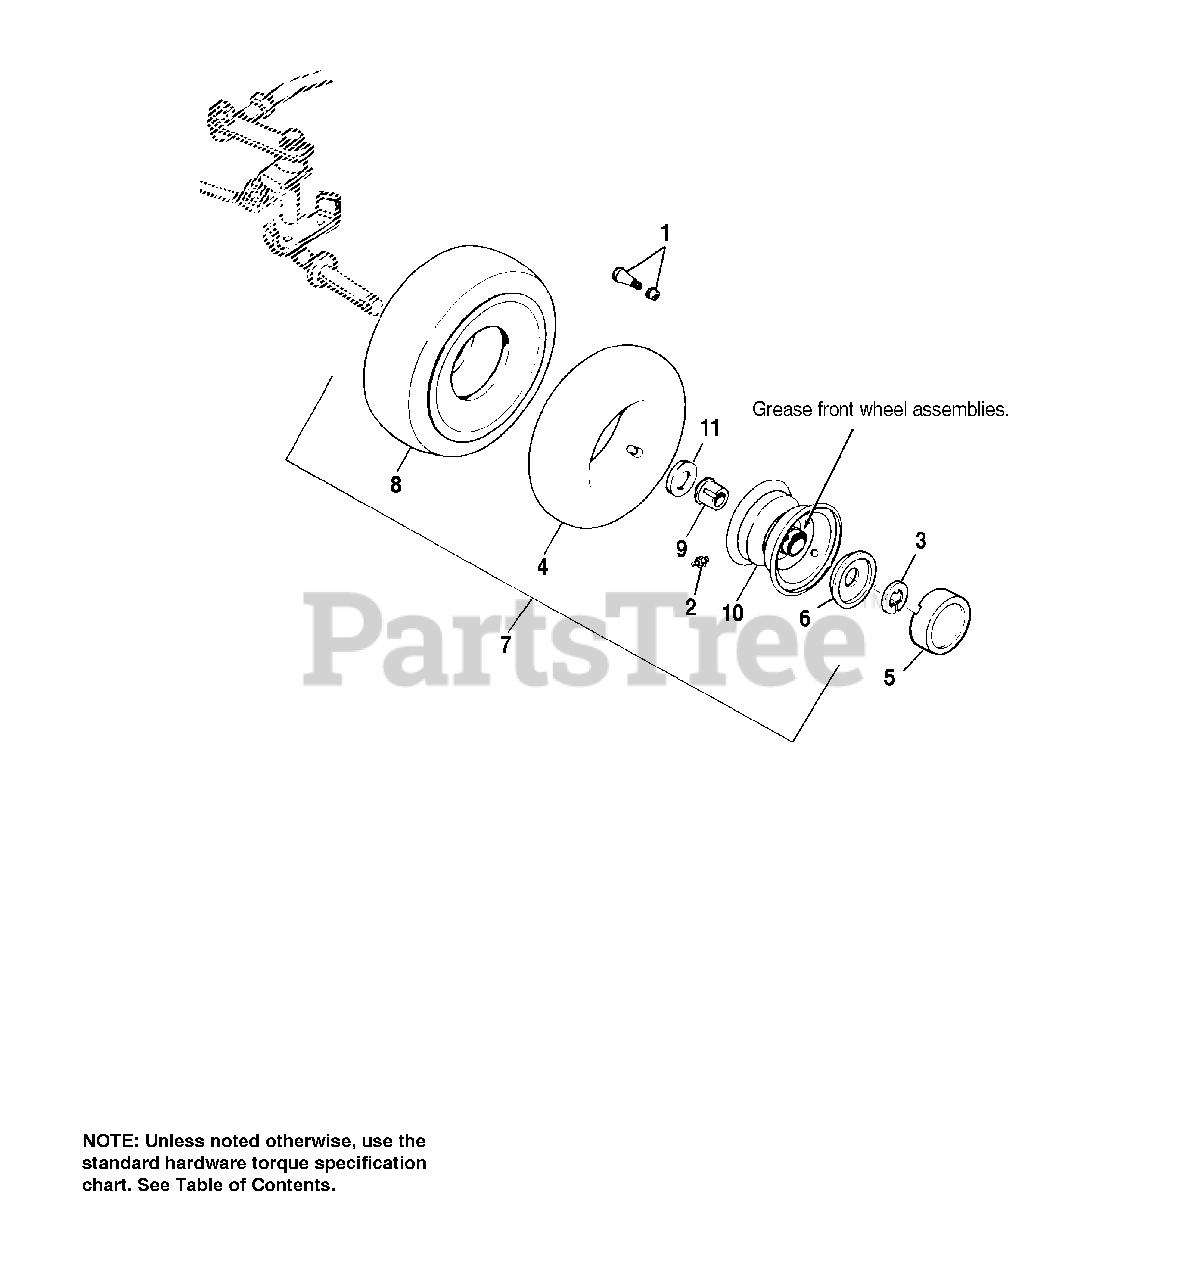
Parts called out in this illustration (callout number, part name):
1	VALVE STEM & CAP
2	GREASE FITTING
3	RING, Retaining
4	TUBE, 4.10/3.50-6
6	RETAINER, Cap, Hub
7	WHEEL & TIRE ASSY. 15 x 6.00-6, Metallic Gray
8	TIRE, 15 x 6.00-6 (Dico)
9	BEARING
10	WHEEL ASSY., Metallic Gray
11	WASHER, 3/4
